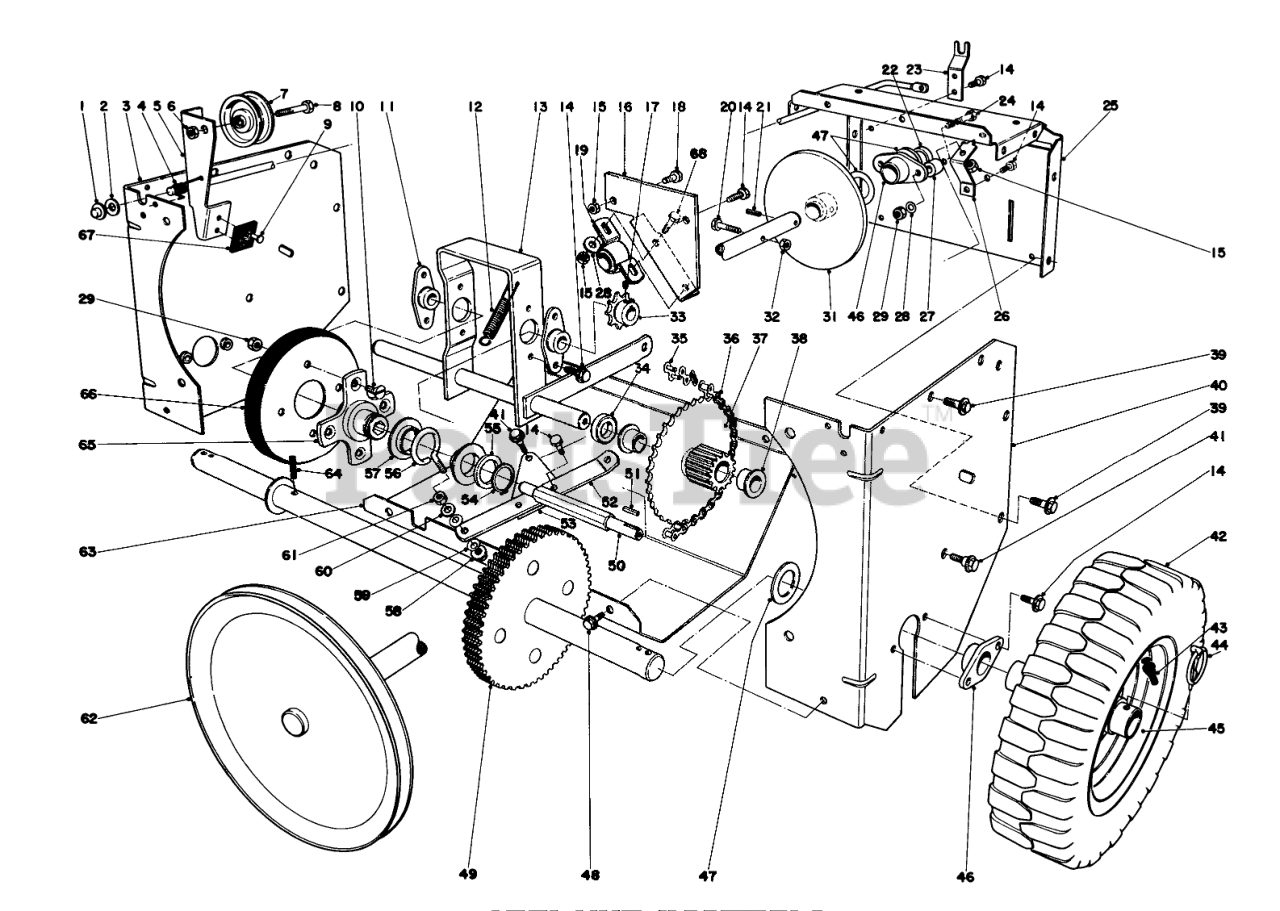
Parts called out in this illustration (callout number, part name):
1	PUSH NUT
2	WASHER-FLAT
3	RH TRACT SIDE PLT R
4	TORSION CLUTCH SPRING
5	Clutch Rod (Incl. Ref. #9 & 67)
6	NUT-HEX
7	PULLEY-IDLER
8	SCREW-HH
9	.185 DIA X .375 RT +
10	5/16-18X5/8 FLT HD MS
11	BEARING-WHEEL, FRICTION
12	TENSION SPRING
13	PIVOT SHAFT WA B
14	SCREW-HWHTF
15	NUT-LOCK, NI
16	SHAFT SUPT BRKT B
17	SCREW-HSH
18	SCREW-HH
19	PILLOW BLOCK BRG
20	SCREW-HH
21	Roll Pin
22	DRIVE SHAFT SPACER
23	CLUTCH ROD SUPPORT
24	SCREW-HH
25	CENTER FRAME R
26	PIVOT BRACKET
27	BRG STANDOFF
28	WASHER-PLAIN
29	Nut
31	FRICTION PLT WA
32	NUT-LOCK, CONE
33	SPROCKET
34	COSHAFT SPACER
35	LINK-CHAIN
36	ROLLER-CHAIN
37	Gear & Bushing (Incl. Ref. #38)
38	BUSHING
39	SCREW-HHFTF
40	LH TRACT SIDE PLT R
41	SHOULDER SCREW
42	Tire
43	STEM-VALVE
44	PIN-LYNCH
45	Wheel
46	AXLE BEARING
47	WASHER
48	SCREW-HWH
49	AXLE & GEAR WA
50	FRICTION WHL SHAFT
51	Square Key
52	SHIFT LINKAGE
53	PIVOT PLATE
54	RING-RETAINING
55	WASHER-THRUST
56	SLIDER RING COLLAR
57	SLIDER RING
58	NUT-LOCK, FLANGE
59	WASHER-SPRING
60	WASHER-FLAT
61	Nut
62	PULLEY/SHFT WA
63	LOWER SHIELD R
64	PIN-ROLL, SLOTTED
65	TRACTION DISC HUB
66	Disc
67	BRAKE PAD
68	SCREW-HH
